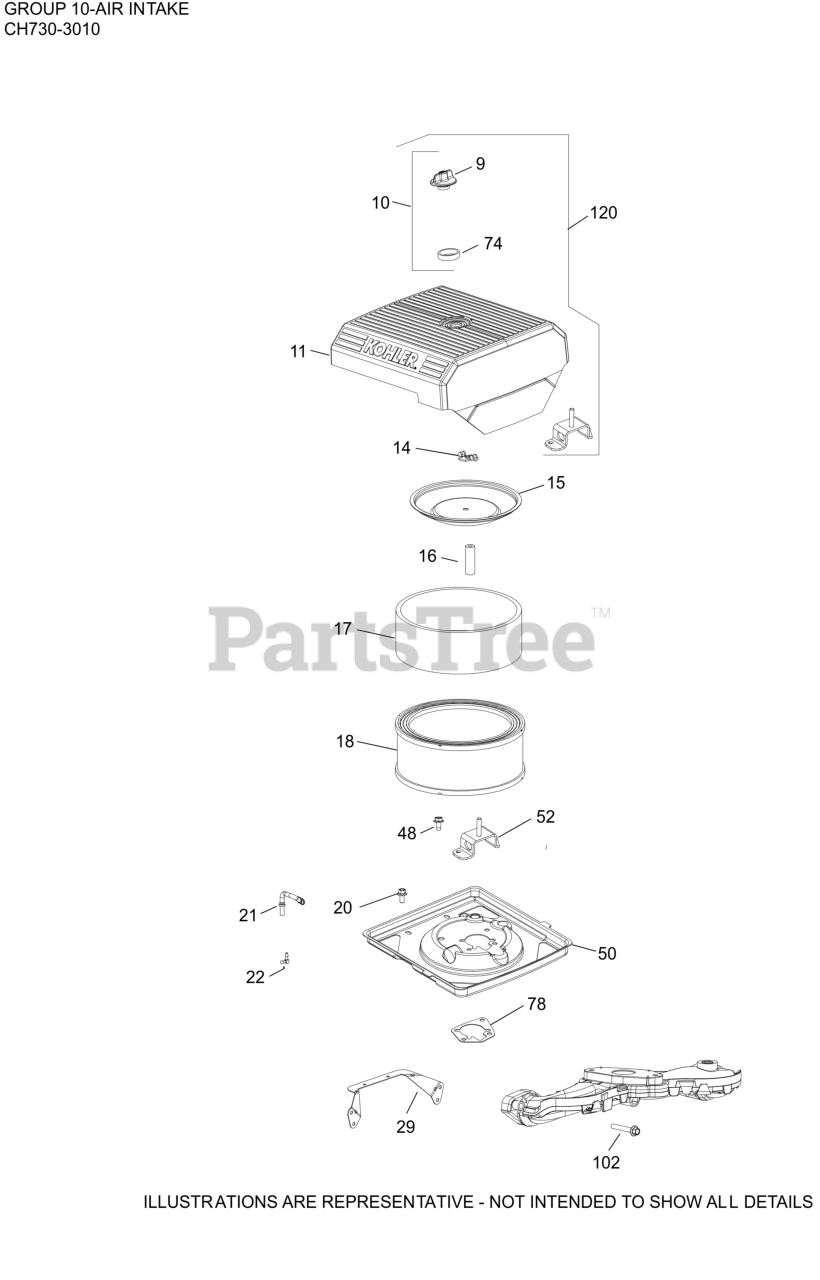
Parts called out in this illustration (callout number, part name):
9	KNOB, COVER
10	KIT, KNOB W/SEAL
11	COVER, AIR CLEANER
14	NUT, WING
15	COVER, INNER AIR CLEANER
16	SEAL BREATHER
17	PRE-CLEANER (HIGH)
18	AIR FILTER ELEMENT
20	SCREW, FLG THD FRM M6X1.0X16
21	HOSE, EVAP
22	CONNECTOR, EVAPORATIVE HOSE
29	AIR CLEANER BRACKET
48	SCREW, THREAD FORMING
50	KIT, AIR CLEANER BASE
52	BRACKET, AIR CLEANER
78	GASKET, AIR CLEANER BASE
102	SCREW, FLG M6X1.0X40
120	KIT, AIR CLEANER COVER
